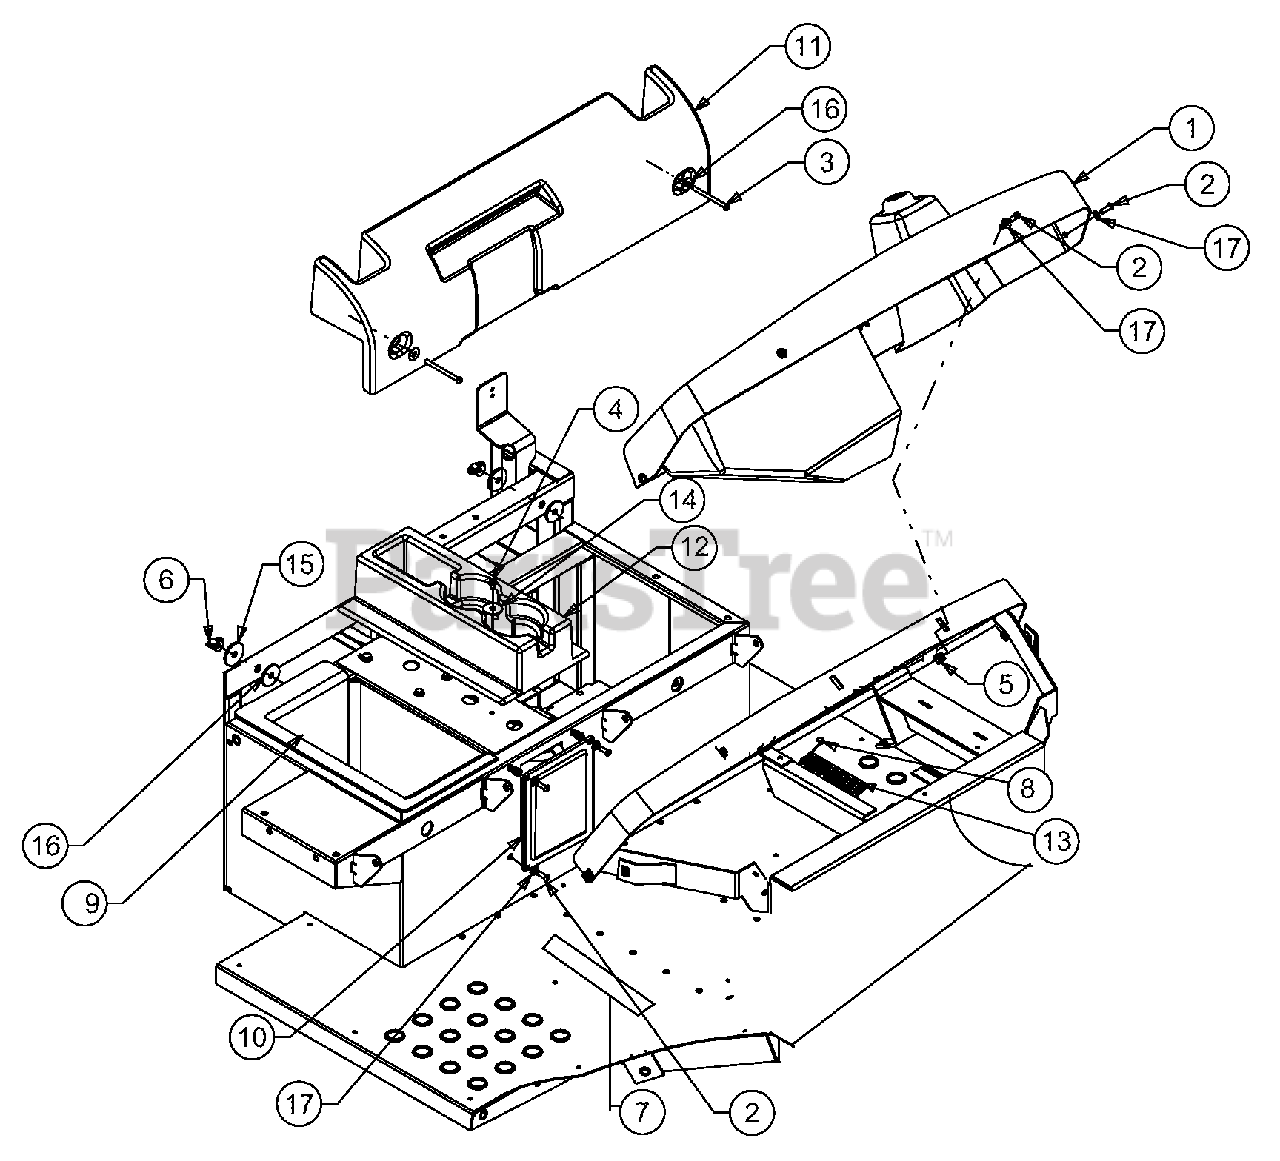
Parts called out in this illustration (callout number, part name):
1	Dash Assembly, Differential Lock
2	Screw, 1/4-20 x .75
3	Screw, 1/4-20 x 3.0
4	Screw, Self-tapping, 1/4-20 x 0.500
5	Nut, Retainer, 1/4-20
6	Wing Nut, 1/4-20 (w/Bell Washer)
7	Anti Skid Foot Pad
8	Retainer Clip .250 x .267
9	Tool Box
10	Panel, Shift Cover
11	Panel, Airbox Cover
12	Console, Cup Holder
13	Pad, Foot
14	Flat Washer, .350 x 1.25 x .06
15	Washer, Rubber, .375 x 1.5 x 1.25
16	Washer, Flat, .3125 x .875 x .04
17	Washer, Flat, .271 x .630 x .065
